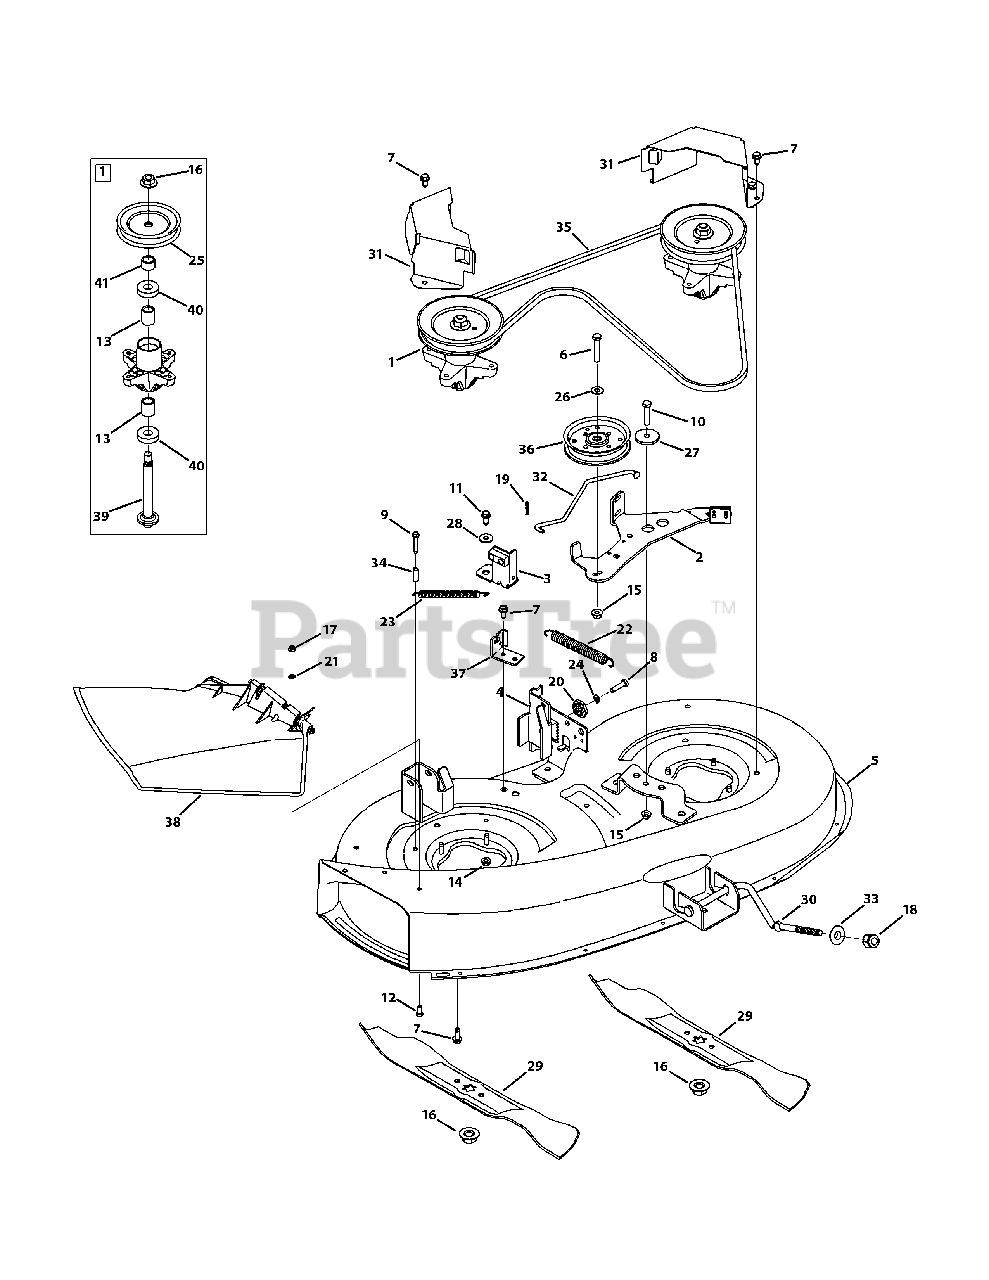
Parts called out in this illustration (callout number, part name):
1	5.75" Pulley Spindle Assembly
2	Deck Brake Assembly
3	Deck Brake Assembly
4	LH Deck Hanger Bracket
5	38" Deck Assembly
6	Hex Screw, 3/8-16 x 1.75
7	Screw, 5/16-18 x .750
8	Hex Screw, 5/16-18 x 1.25
9	Screw, 1/4-20 x 1.50
10	Hex Screw, 3/8-16 x 1.25
11	Hex Screw, 5/16-18 x .75
12	Hex Screw, 1/4-20 x .62
13	Spacer, .80 x 1.10 x 1.322 LG
14	Flangelock Nut, 5/16-18
15	Flangelock Nut, 3/8-16
16	Flange Nut, 5/8-18
17	Flangelock Nut, 1/4-20
18	Flangelock Nut, 1/2-13
19	Cotter Pin, .072 Diameter
20	Deck Adjuster Gear
21	Push Nut, .25 x .50
22	Extension Springing, .75 x 6.375
23	Extension Springing, .500 x 6.375
24	Lock Washer, 5/16
25	Deck Pulley, 5.75
26	Flat Washer, .406 x .875 x .059
27	Shoulder Spacer, .8840 x .190
28	Shoulder Spacer, .5000 x .1475
29	3 in 1 Blade
30	38" Front Adjust Deck Rod
31	Belt Cover
32	38" Brake Control Rod
33	Deck Lift, Pivot Cup
34	Spacer, .260 x .375 x 1.030
35	V Type Belt
36	Idler Pulley
37	Deck Engage Cable Bracket
38	Chute Assembly
39	Spindle Shaft, 5.50
40	Ball Bearing, .787ID x 1.85 OD x .551
41	Spacer, .820 x 1.150 x .480 LG
